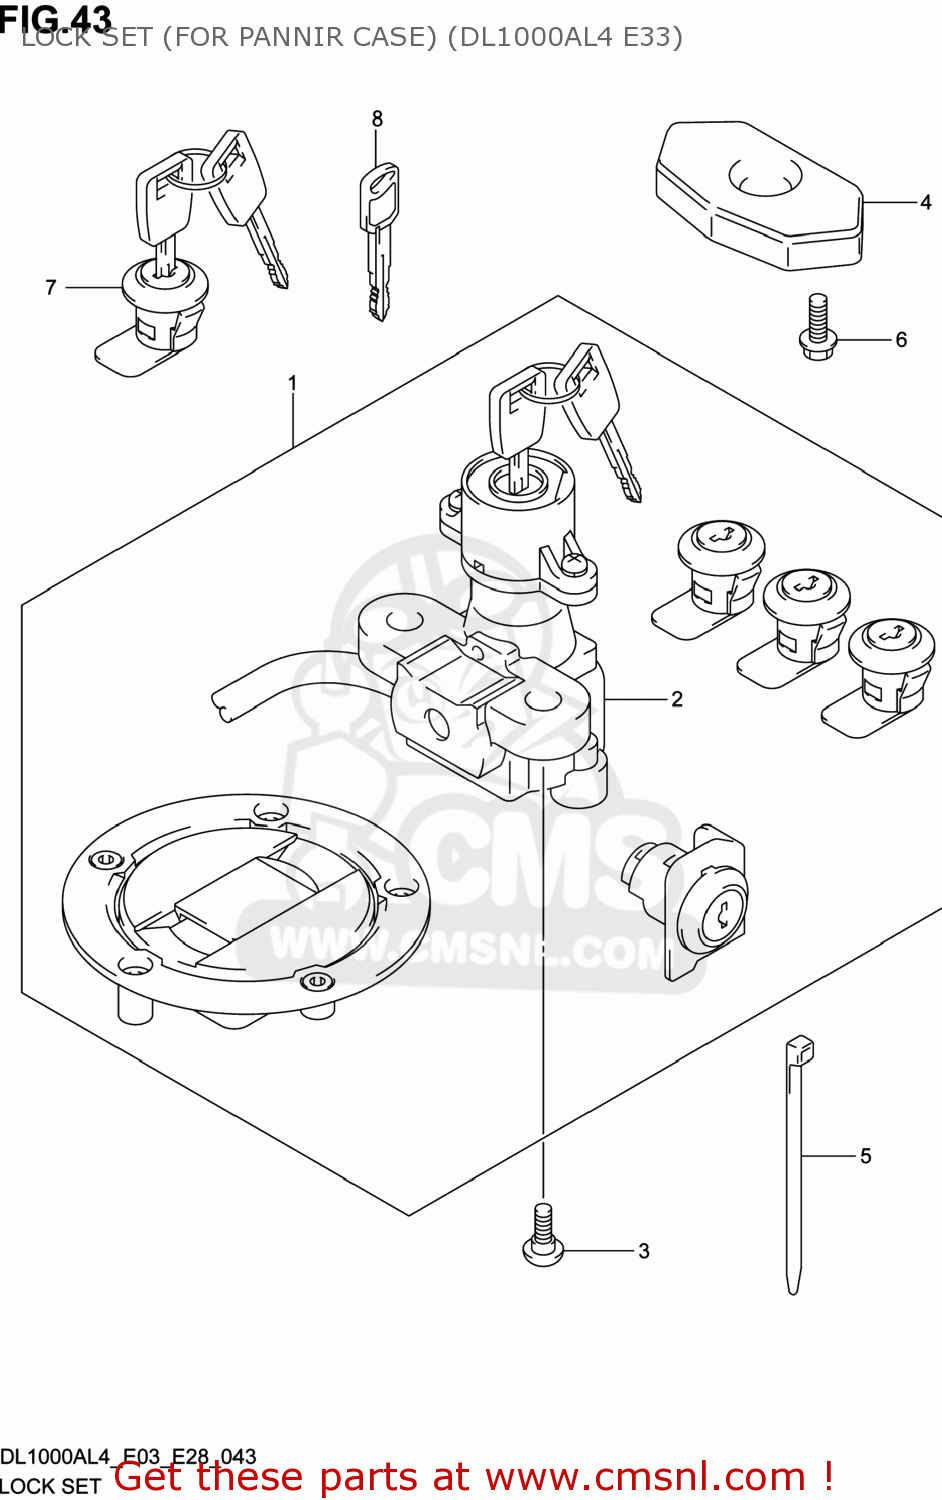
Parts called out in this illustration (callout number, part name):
1	LOCK SET
2	LOCK ASSY,STEERING
3	BOLT(8X20)
4	COVER,STEERING LOCK
5	CLAMP(L:145)
6	BOLT
7	LOCK SET,CASE
8	KEY,BLANK
